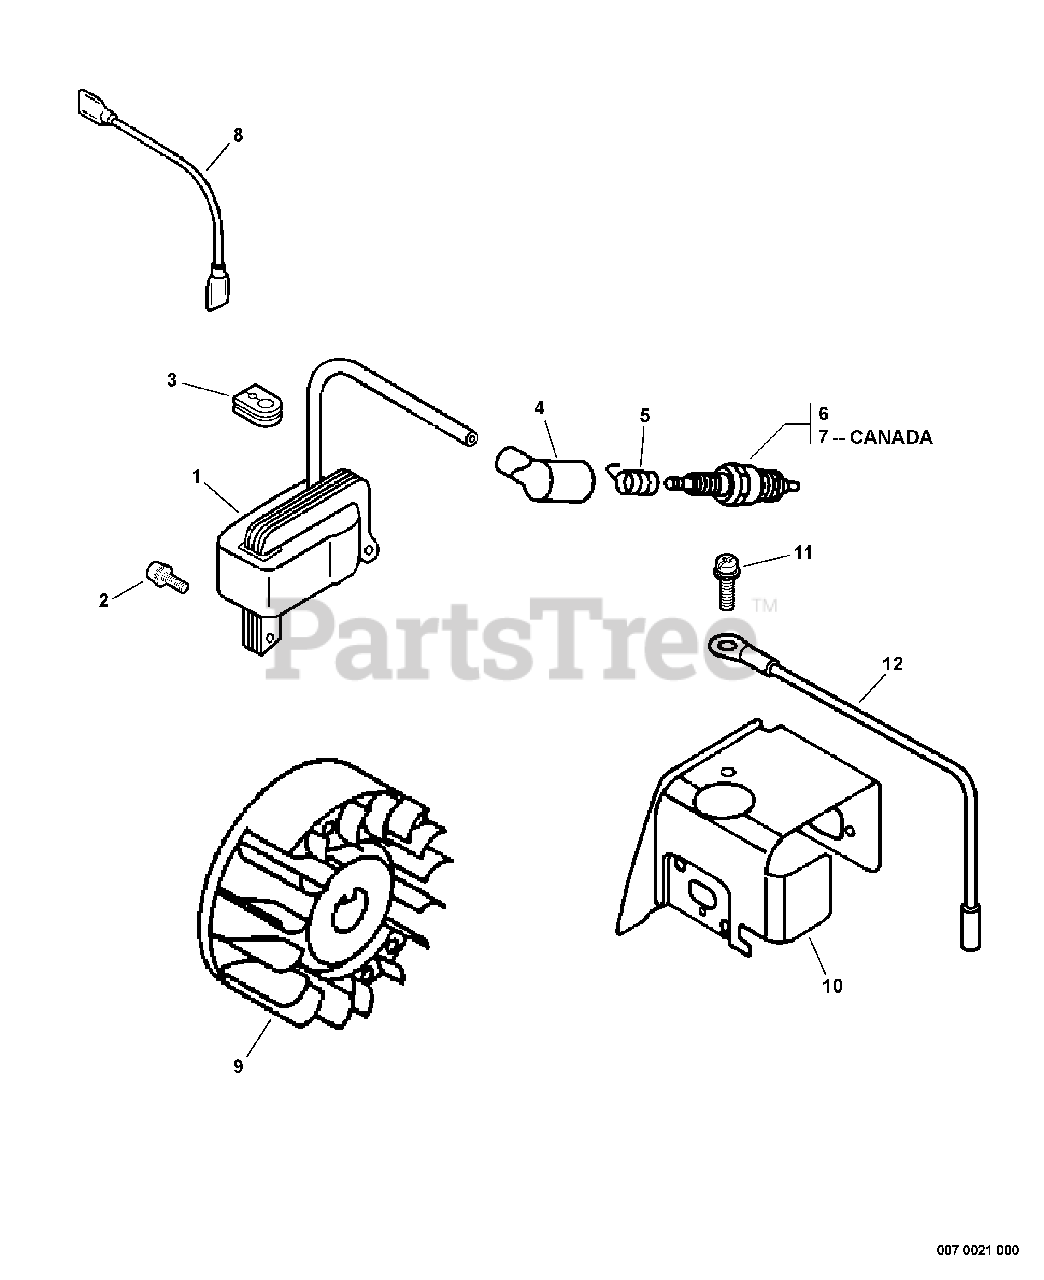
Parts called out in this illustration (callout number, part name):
1	COIL, IGNITION
2	SCREW - 5X16
4	CAP, SPARK PLUG
5	TERMINAL, SPARK PLUG CAP
6	SPARK PLUG -- BPM-8Y
7	SPARK PLUG -- BPMR-8Y
8	LEAD - IGNITION
9	FLYWHEEL
10	SHIELD, CYLINDER
11	SCREW - 5X10
12	LEAD - GROUND
